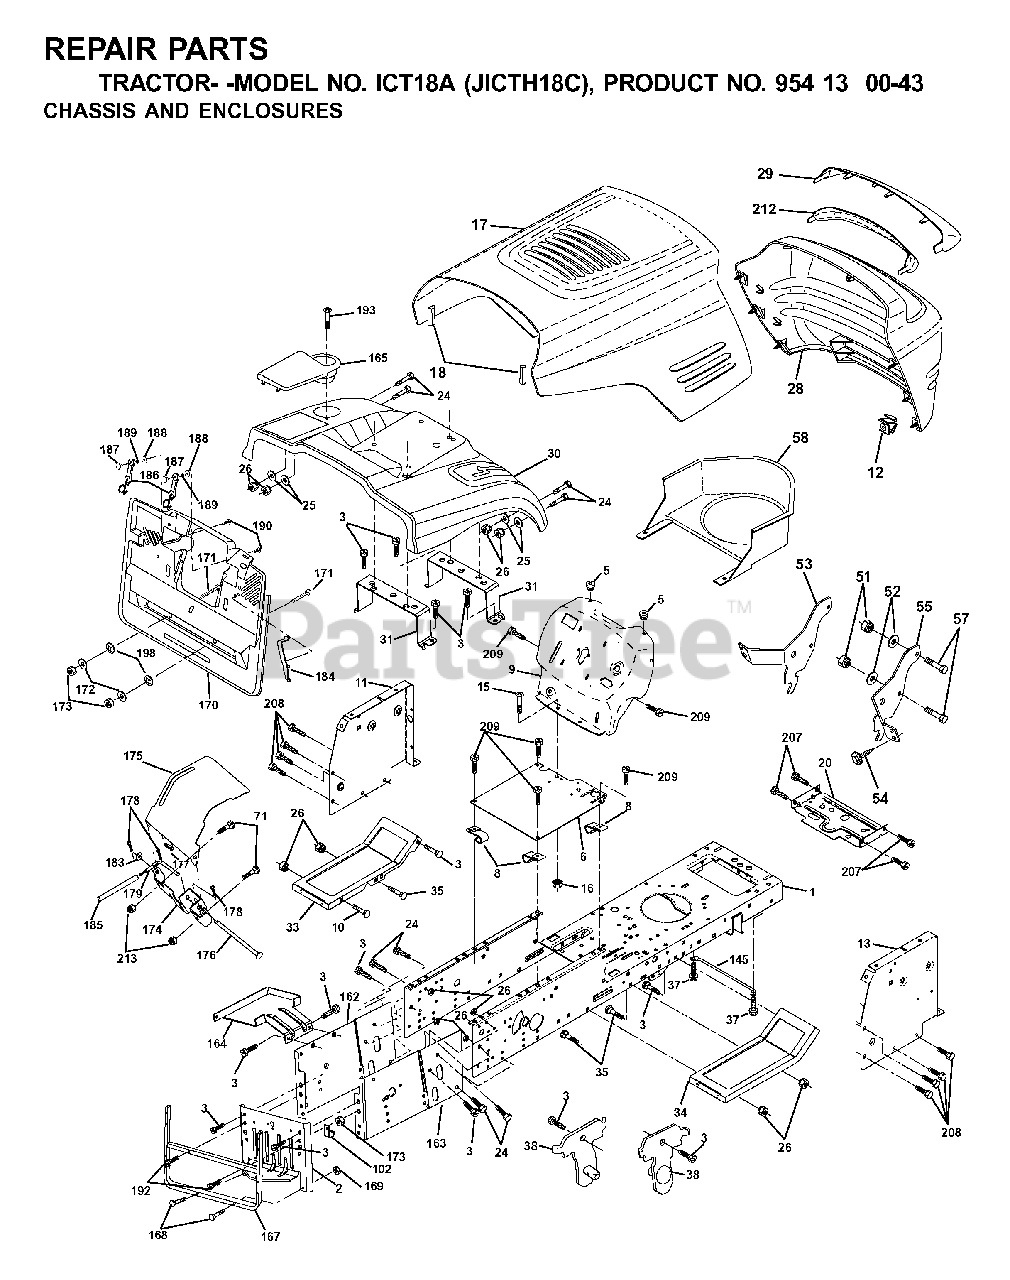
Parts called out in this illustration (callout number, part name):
1	CHASSIS STAMPING
3	SCREW 3/8-16X3/4
5	BUMPER.RUBBER.HOOD
6	SADDLE FLAT
8	CLIP,INSULATOR
10	BOLT D
11	PANEL DASH LH
13	DASH PANEL RH
16	NUT
18	BUMPER HOOD T
20	PLATE MTG
25	WASHER
26	NUT
31	BRACKET SUPPORT FENDER
38	BRACKET
51	LOCKNUT
57	BOLT
58	DUCT, INTAKE AIR
102	CLIP T
145	ROD PIVOT CHASSIS/HOOD
164	SUPPORT
168	BOLT.ROUND.HEAD.SQUARE.NECK
169	NUT T
170	BACKPLATE ASM
171	BOLT
172	WASHER
176	HINGE PIN
177	SPRING COVER LH
178	COTTER PIN
179	ROD PIVOT
180	BOLT RB
181	LOCKNUT
185	TUBE LEVER
186	LATCH ASSY
187	WELDNUT
189	LOCKWASHER
193	SCREW, TRUSS 1/4-20 X 3/4"
207	SCREW, 5/16-18 X 1/2
208	SCREW 3/8-16X1/2
209	SCREW, 3/8-16X3/4
213	NUT.CROWNLOCK.1/4
